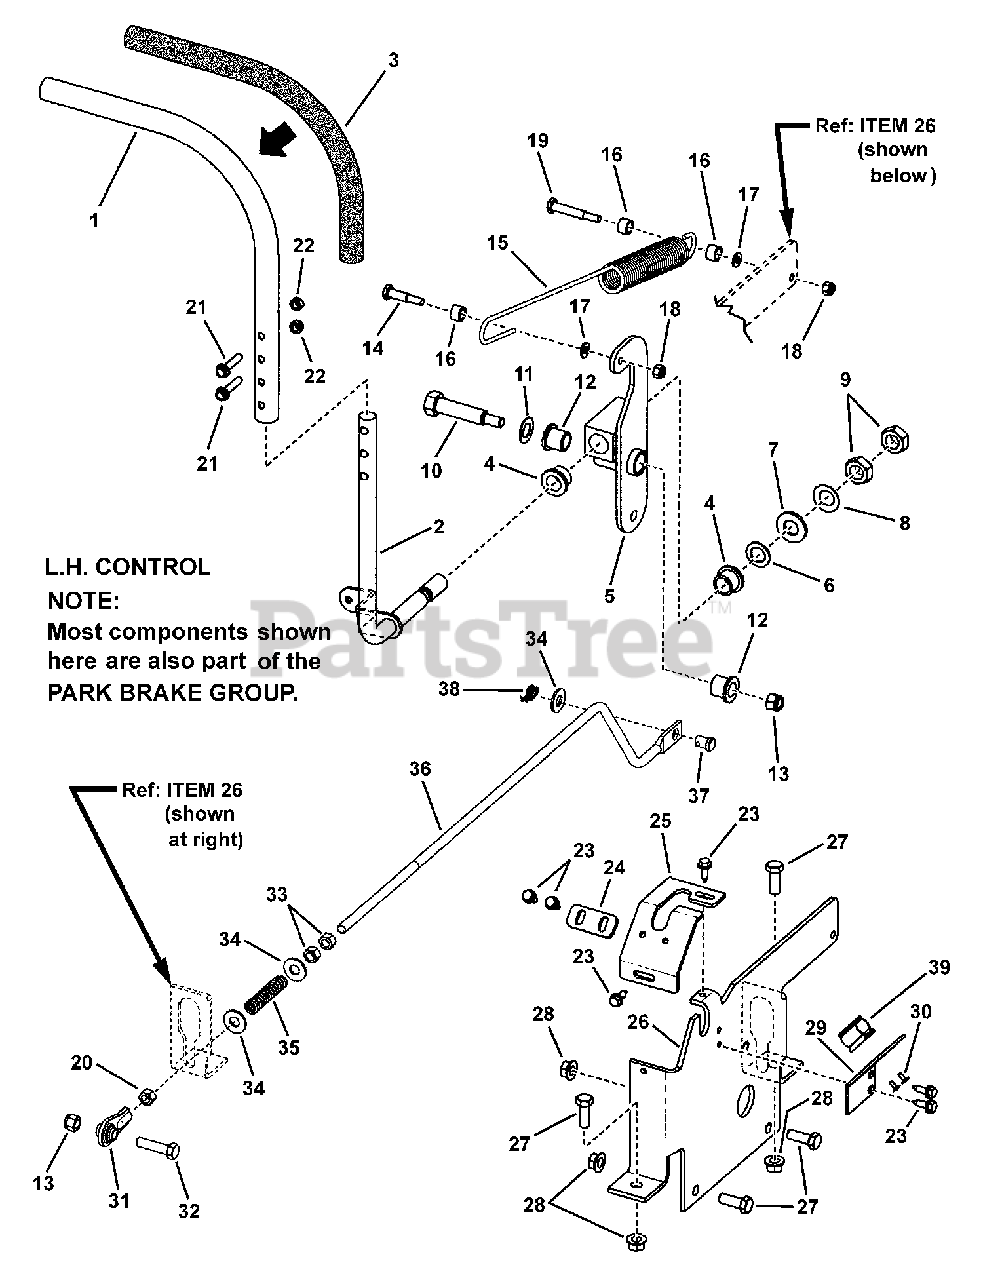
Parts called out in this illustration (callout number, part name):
1	HANDLE
2	WELD, Control Arm, LH, Yellow
3	GRIP, Handle
4	BUSHING, ST, Powdered Metal
5	WELD, Control Bracket, LH, Yellow
6	WASHER, Nylon, 5/8 ID.X1"OD.X.065
7	WASHER, .668X1.324X.098 YZ
8	WASHER, Bellville, .64X1.125X.028
9	NUT, Hex, Jam, 5/8F ZP
10	SHOULDER BOLT, 3/8C
11	WASHER, Thrust, .562 X 1.000 X .031
12	BEARING, Flange, 9/16
13	NUT, Hex, 3/8C, Nylock YZ
14	SHOULDER BOLT, 5/16 X 1/4C
15	* SPRING, Extension, RTN, ERZT
16	SPACER, .33 X .50 X .355, Yellow
17	WASHER, 1/4" ID, Harden
18	NUT, Hex Lock Nylon, 1/4C YZ
19	SHOULDER BOLT, 5/16 X 1/4C
20	NUT, Hex, Jam, 3/8-24
21	CAPSCREW, Hex Head, 1/4C X1-1/4" GR5 YZ
22	NUT, Hex Center Lock, 1/4C YZ
23	CAPSCREW, Hex Head Flange Taptite, 1/4C X3/4 BZ
24	PLATE, Fwd/Rev Adjust
25	TRACK, Control Stick, LH
26	BRACKET, Control, LH
27	CAPSCREW, Hex Head, 3/8C X1 GR5 YZ
28	NUT, Hex Flange Lock, 3/8C YZ
29	BRACKET, Rod Holder, RZT
30	POP RIVET, 1/8X3/8
32	CAPSCREW, Hex Head, 3/8C X1-1/2 GR5 YZ
33	NUT, Hex, 3/8F GR5 YZ
34	WASHER, .438X1X.084 YZ
35	SPRING, Brake Compression
36	ROD, Link Fwd/Rev
37	CLEVIS PIN, 7/16 X 1
38	PIN, Cotter, 1/2 Self, YZ
39	CLIP, Spring
